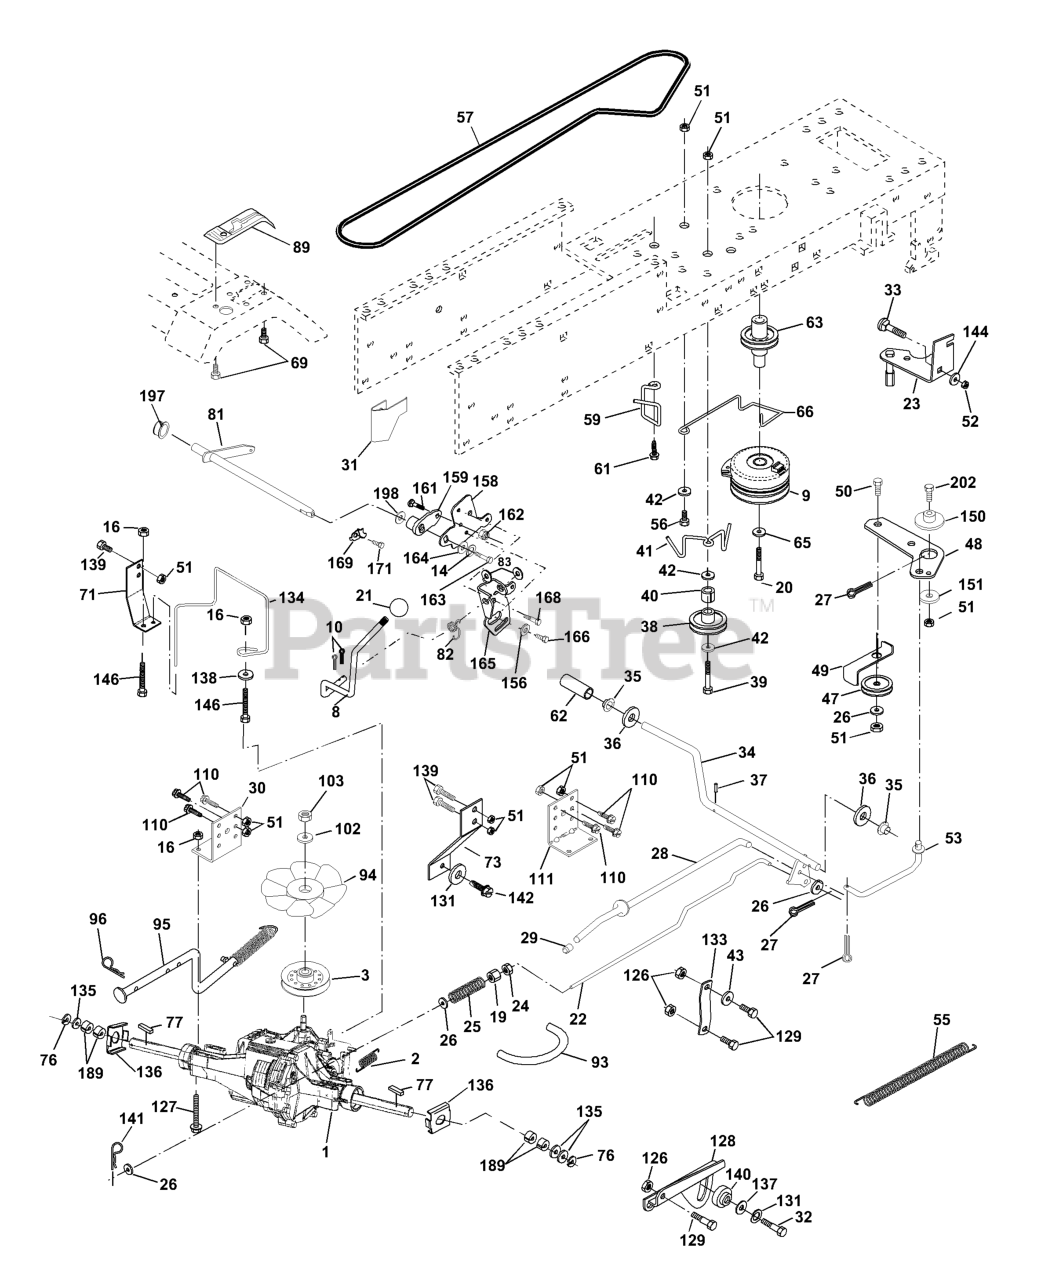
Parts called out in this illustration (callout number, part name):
2	SPRING BRAKE
3	PULLEY, TRANSAXLE
8	ROD SHIFT FENDER
9	ELECTRIC CLUTCH
10	PIN COTTER
14	LOCKWASHER
16	NUT.71038.31-18.HEX.NYLOCK
19	NUT
20	BOLT HEX
21	KNOB.DELUXE.(PISTOL.GRIP).BLAC
24	Nut, Hex Jam 3/8-16
25	SPRING ROD LT
26	WASHER
27	COTTER PIN
28	ROD BRAKE PARK LT
29	PLUNGER CAP
30	BRKT TRANS LH
31	KEEPER BELT LH
32	BOLT
33	RP BOLT 5/16-18 X3/4 ZN/YEL GR
34	SHAFT, FOOT PEDAL
35	BEARING.NYLON
36	WASHER LT
37	DRIVE PIN
38	FLAT IDLER PULLEY
41	KEEPER.BELT.IDLER.FLAT
42	WASHER
43	WASHER T
47	IDLER PULLEY
48	BELLCRANK, CLUTCH
49	RETAIN BELT
50	BOLT
52	LOCKNUT
53	LINK, CLUTCH LT
55	SPRING, RETURN LT
59	KEEPER, BELT CENTER
61	SCREW 3/8-16X3/4
62	PEDAL COVER T
63	ENGINE PULLEY
65	LOCKWASHER
66	BELT KEEPER
69	SCREW.HI-LO.CONSOLE
71	STRAP.TORQUE.LH.HYDRO
73	STRAP.TORQUE.RH.HYDRO
76	E RING HYT
77	SQ KEY STD
81	SHIFT.ASM.CROSS.TAPER
82	SPRING,TORSION
83	WASHER
89	FENDER CONSOLE
93	LINE FUEL HYD 4"
94	FAN 7" HYDRO
95	CONTROL.ASM.BYPASS.HYDRO-3000
96	RETAINER M
103	NUT.HEX.1/2-20
111	BRKT TRANS RH
127	BOLT HEX FLGHD 5/16-18X3 GR. 5
129	BOLT, SHOULDER LT
131	LOCKWASHER
133	LINK, TRANSAXLE
134	BELT GUIDE
136	WASHER.AXLE.FLANGE.HG-3000
138	Washer 11/32 x 1.25 x 16 Ga.
142	Bolt 5/16 x 24 x 1
144	Washer 11/32 x 5/8 x 16 Ga SD
146	Bolt Hex Flghd 5/16-18 x 2-1/4
150	BUSHING.BELLCRANK.GRD.DR
151	WASHER 12/32X2X10GA
156	WASHER.SRRTD.5/16
158	BRACKET
159	HUB
161	BOLT
162	NUT.CROWNLOCK.1/4
163	Bolt Hex Fin 1/4-20 Unc x 1 Gr 5
164	Washer 5/8 x .281 x 10 Ga
165	RP BRACKET
168	BOLT.SHOULDER.5/16-18X
169	PLATE FASTENING LT
171	SCREW LT
189	WASHER, SPACER AXLE
197	NYLINER SNAP 5/8" ID
198	WASHER.NYL.7/8IDX.105"HYD CR
202	BOLT.3/8-16X1.50
